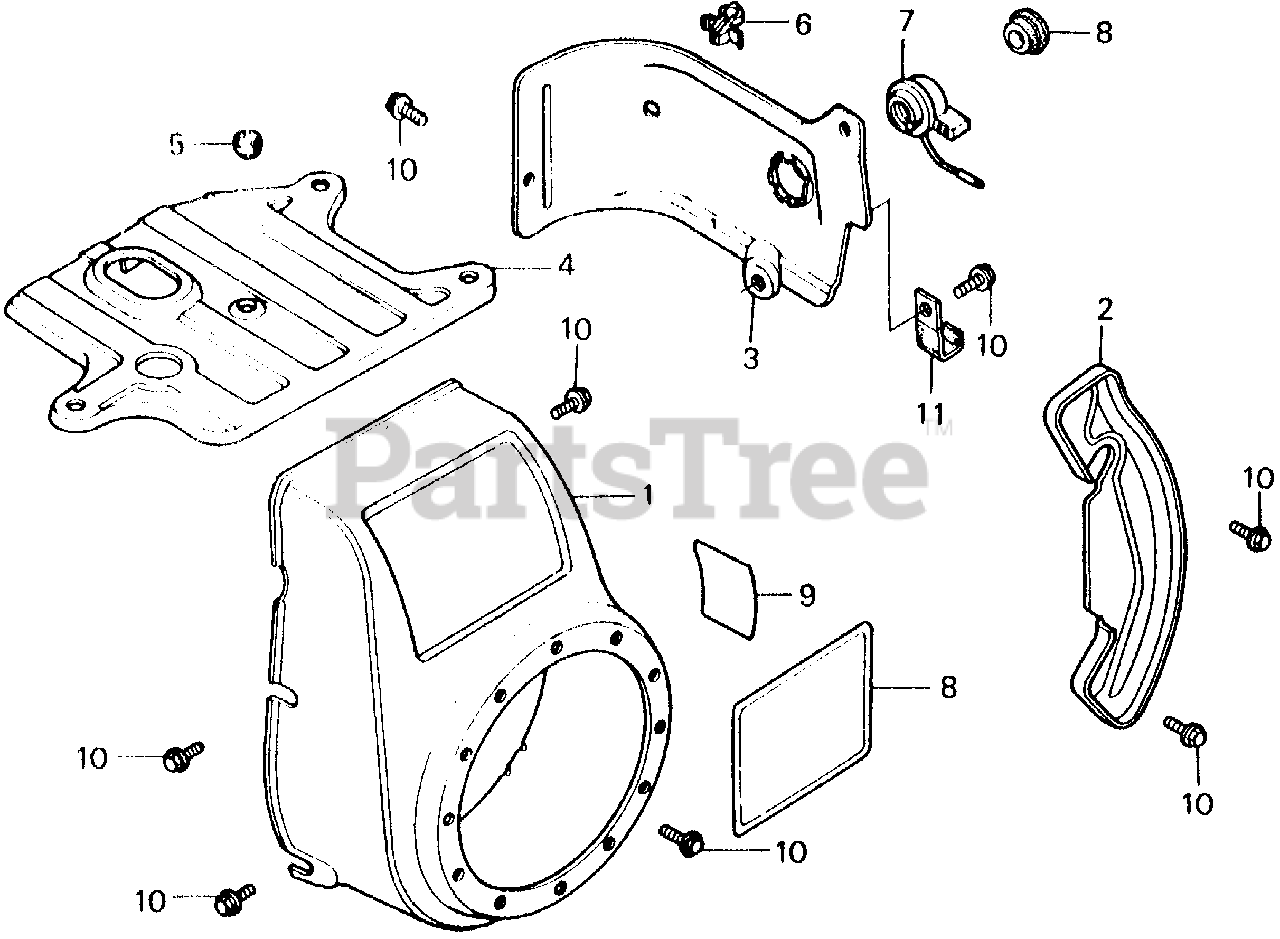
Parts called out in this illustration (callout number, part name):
1	COVER, FAN *R8* (BRIGHT RED)
2	PLATE, SIDE
4	COVER, TOP
5	GROMMET, TOP COVER
6	CLIP, IGNITION WIRE (8MM)
7	SWITCH ASSY., ENGINE STOP
9	MARK, OIL CAUTION
10	BOLT, FLANGE (6X12) (CT200)
11	CLIP, CABLE
